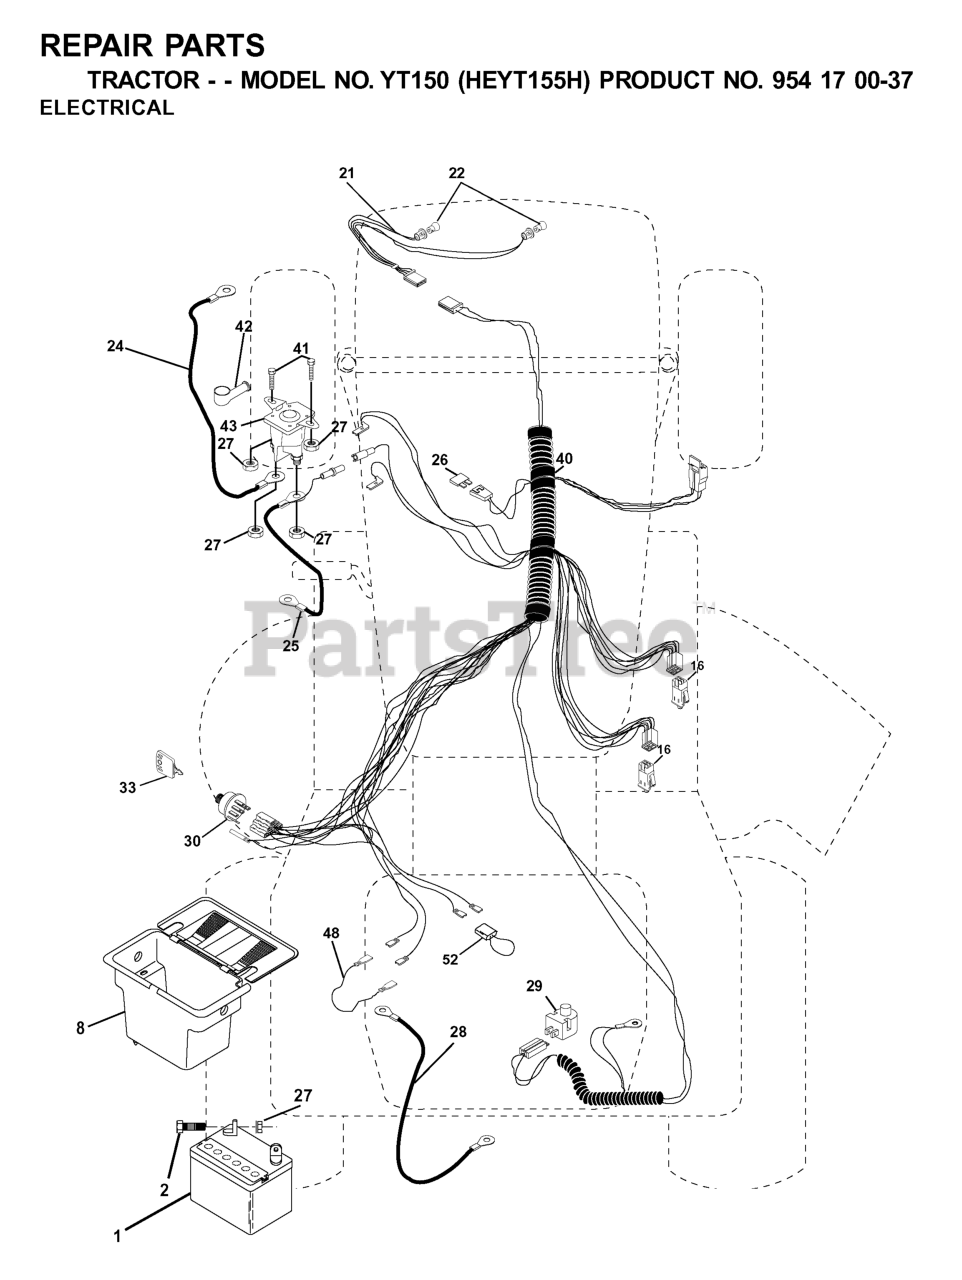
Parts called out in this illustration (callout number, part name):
1	BATTERY 12 VOLT 25 AMP
2	BOLT.HEX.1/4.X.3/4.DICHROMATE
8	CASE BATTERY MECH HINGE
16	SWITCH INTERLOCK
24	BATTERY CABLE GT
25	CABLE BATTERY
26	FUSE 20AMP
27	NUT
28	CABLE T
29	RP.SWITCH.PLUNGER.NC.GRAY
30	IGNITION SWITCH
33	KEY MLD GEN DELTA
40	HARNESS, IGN. LTH120
41	BOLT
42	TERMINAL COVER
43	REPL BY 532 1461-54
48	ADAPTER.AMMETER
52	WIRE PROTECTION LOOP
